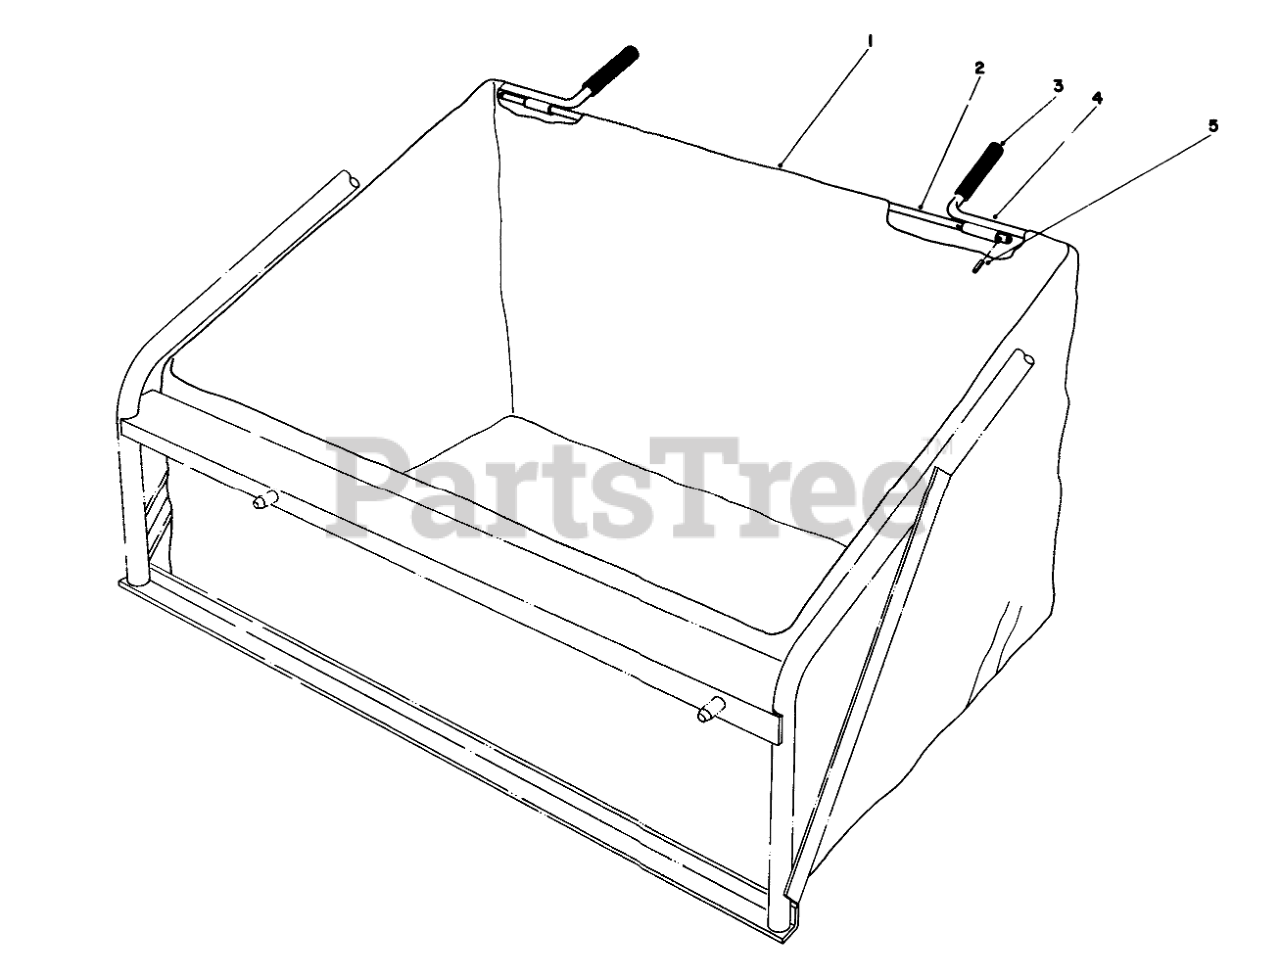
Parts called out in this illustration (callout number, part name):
1	Bag-Leaf Catcher
2	BAG FRAME ROD
3	BAG HANDLE GRIP
4	BAG FRAME WA B
5	PIN-ROLL
